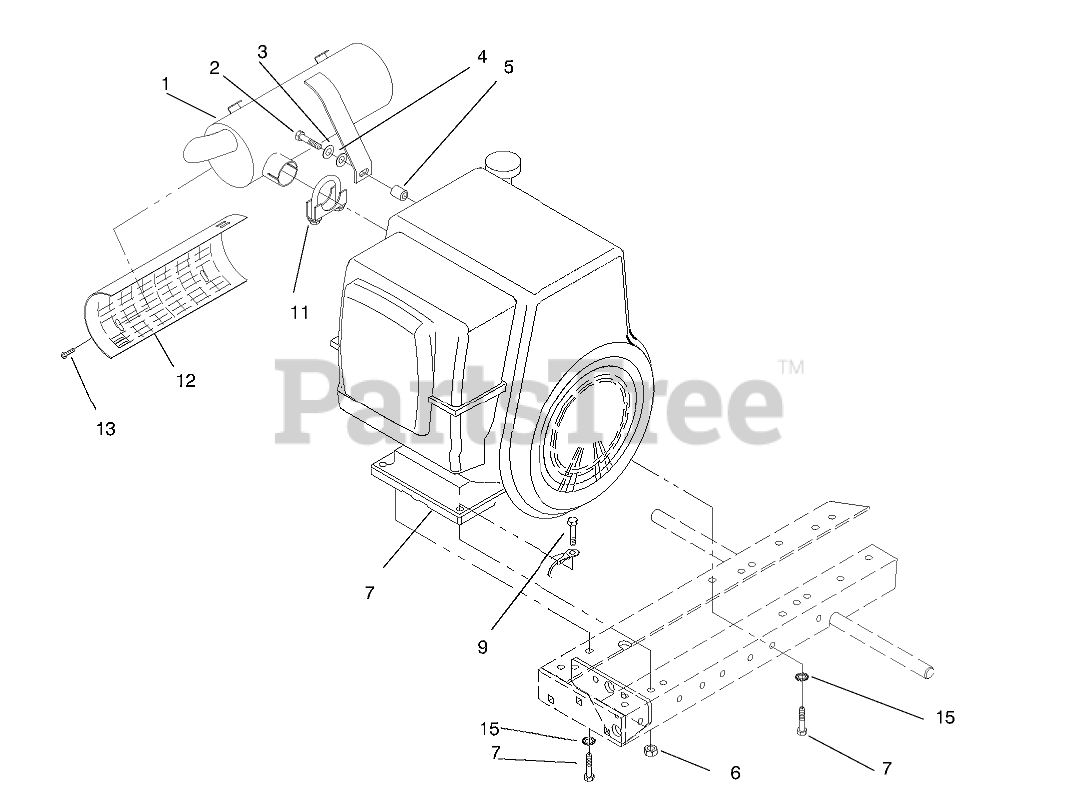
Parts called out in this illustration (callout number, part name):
1	MUFFLER
2	SCREW-HH
3	WASHER-LOCK
4	WASHER-PLAIN
5	SPACER
6	NUT-LOCK, NI
7	SCREW-HH
9	SCREW-HH
10	Engine-14HP
11	CLAMP-1 1/2
12	SHIELD-HEAT
13	SCREW
14	WIRE GROUND
15	WASHER-LOCK
